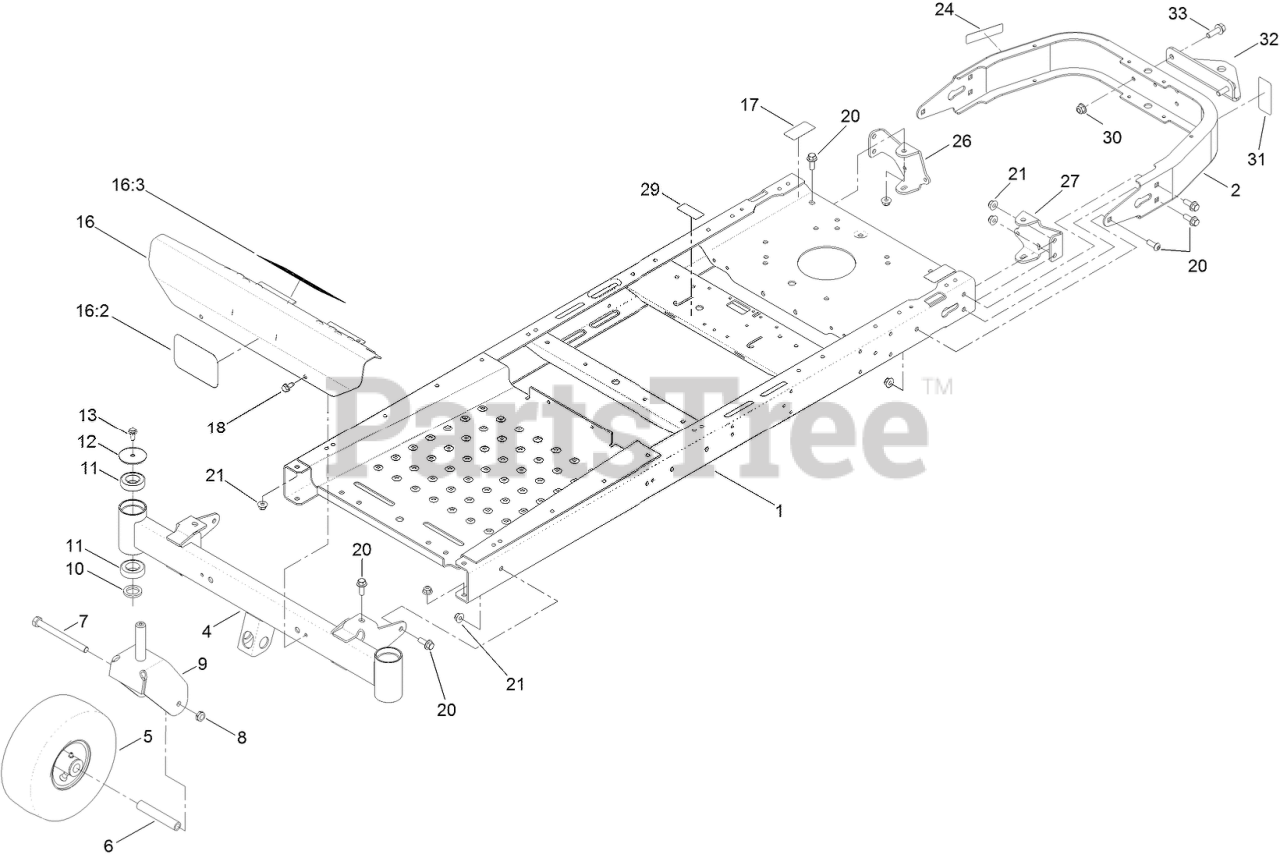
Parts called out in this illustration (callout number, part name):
2	BUMPER-REAR
4	AXLE-FRONT
5	Caster Wheel ASM
6	BUSHING-SPANNER
7	SCREW-HH
8	NUT-LOCK, NI
9	FORK-CASTER
10	WASHER-THRUST
11	BEARING-BALL
12	WASHER
13	SCREW-HHF
16	FOOTREST ASM
16:3	DECAL-DANGER
17	DECAL-BYPASS
18	SCREW-HWHTF
20	SCREW-HHF
21	NUT-HF, NI
24	DECAL-ARRESTER, SPARK
26	MOUNT-HYDRO, REAR (RH)
27	MOUNT-HYDRO, REAR (LH)
29	DECAL-LOCATION, SERVICE DEALER
30	NUT-HF, NI
32	BRACKET-HITCH
33	SCREW-HHF
